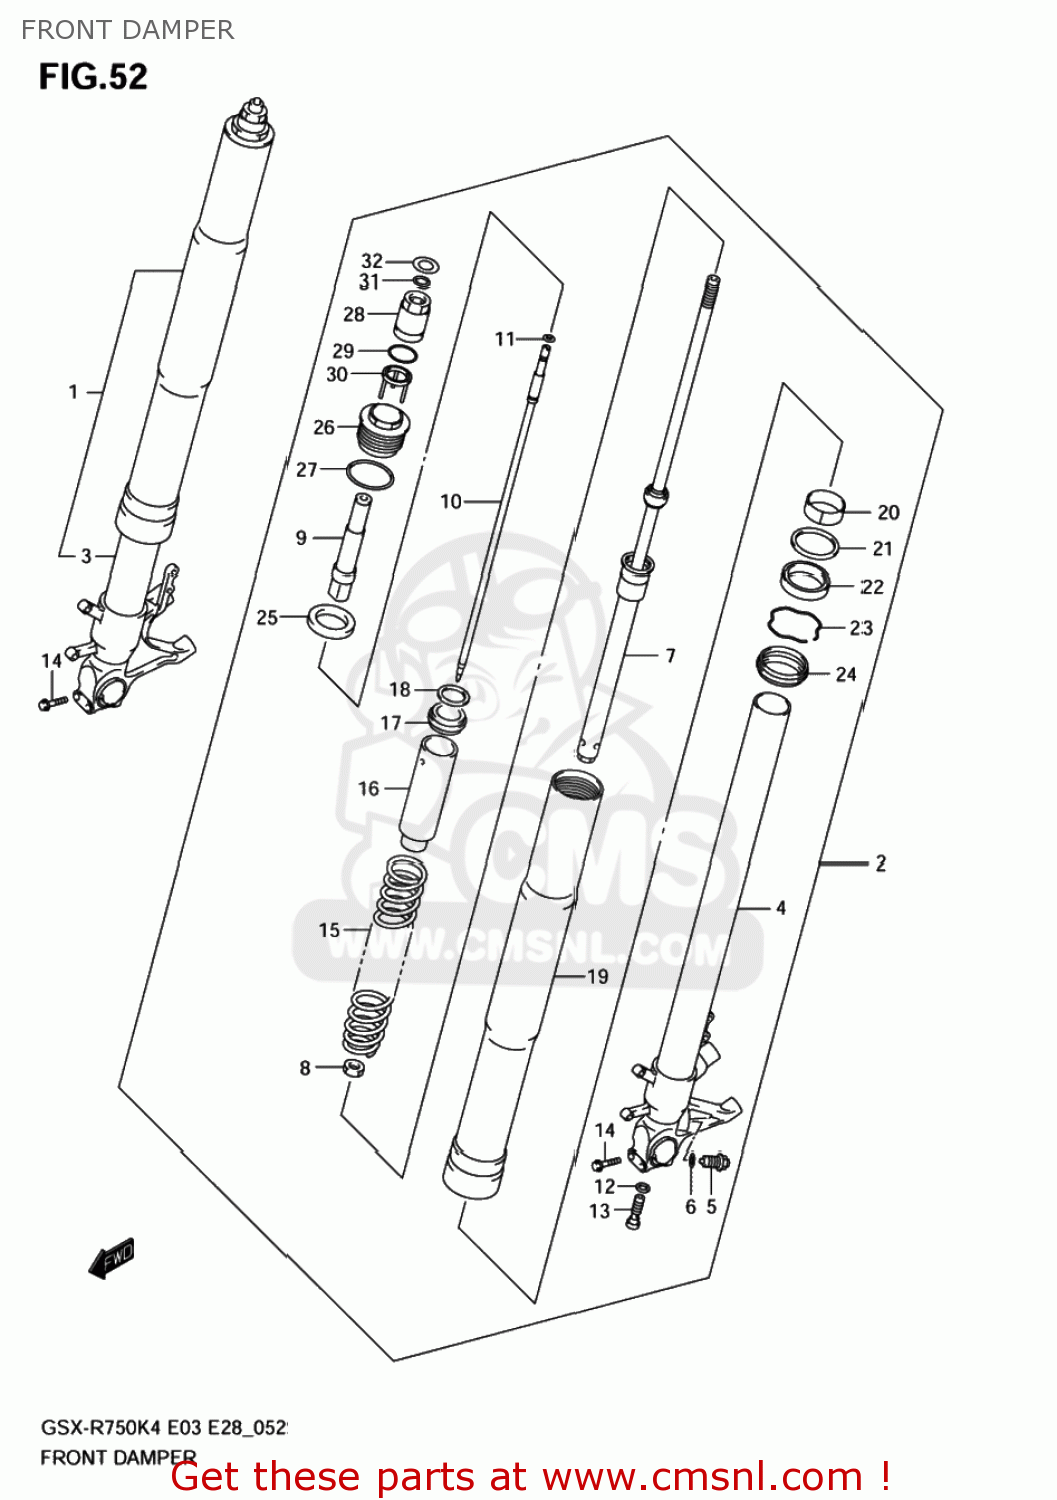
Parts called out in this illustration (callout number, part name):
1	DAMPER ASSY,FR FORK,R
2	DAMPER ASSY,FR FORK,L
3	TUBE,INNER,R
4	TUBE,INNER,L
5	PIECE,ADJUST
6	O RING(D:2.5,ID:13.8)
7	ROD,FR DAMPER
8	NUT
9	CASE,ADJUSTER
10	PIECE,ADJUST
11	O RING(D:1.9,ID:3.8)
12	WASHER(10X15X1.5)
13	BOLT
14	BOLT
15	SPRING,MAIN
16	COLLAR,SPRING
17	GUIDE,SPRING UPR
18	GUIDE,SPRING
19	TUBE,OUTER
20	BUSH,GUIDE
21	SPACER,SEAL
22	SEAL,OIL
23	CIRCLIP,FORK OIL SEAL
24	SEAL,DUST
25	RUBBER,SEAT
26	BOLT,FORK
27	O RING,FORK BOLT
28	ADJUSTER,SPRING
29	O RING
30	PLATE,SPRING ADJUSTER
31	RING,STOPPER
32	LABEL,ADJUST PIECE UPR
